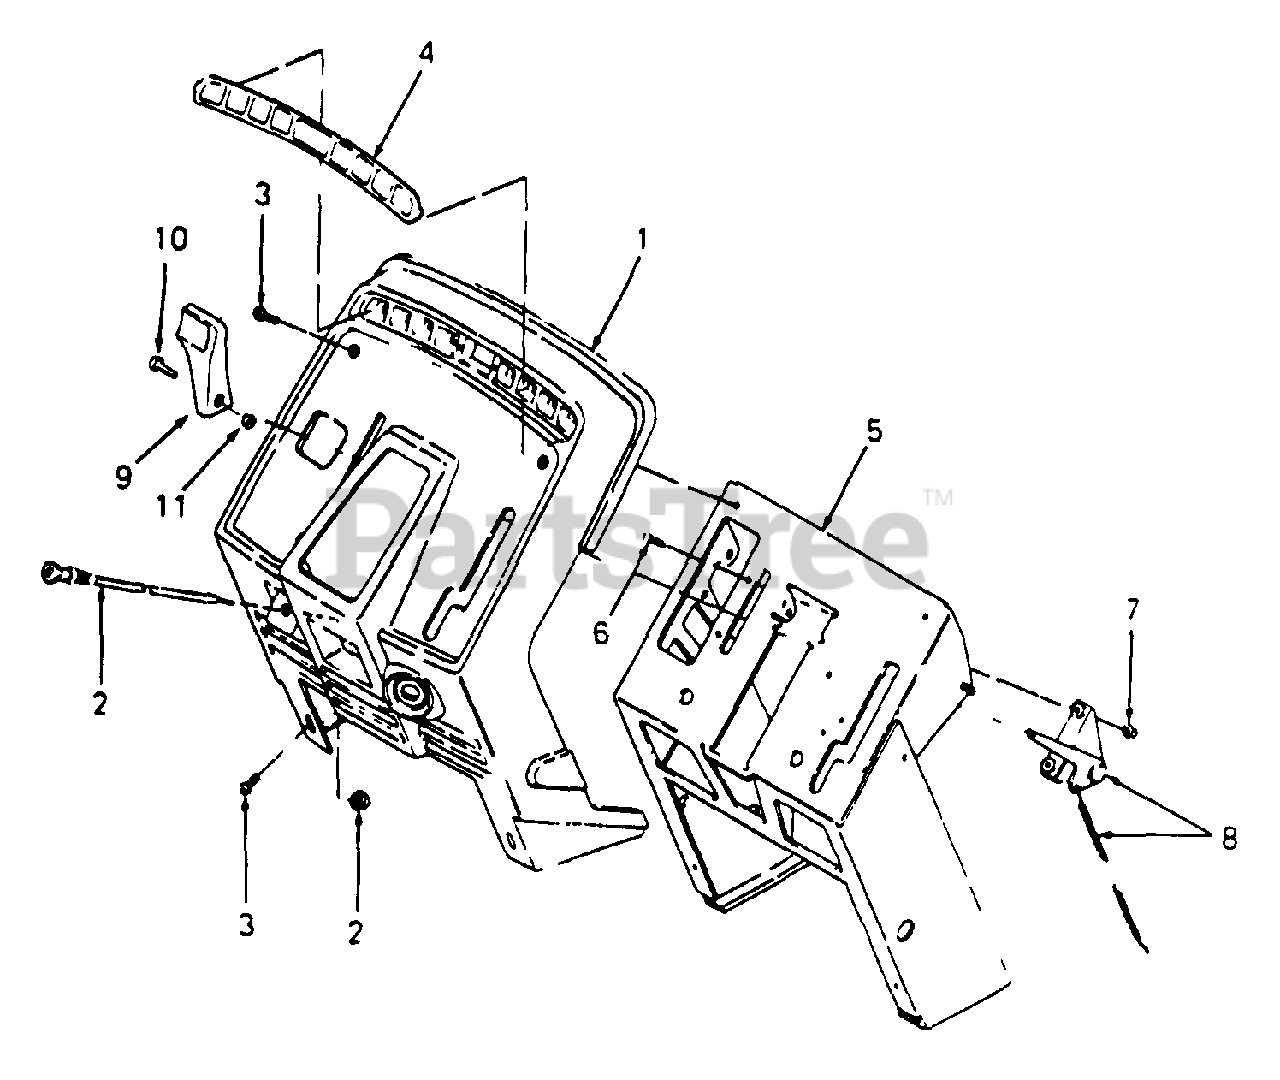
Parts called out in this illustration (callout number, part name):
1	Panel, Instrument
2	Choke Cable w/Nut
3	Screw, Pan Hd Cutting, #10-24 x .75 Lg
4	Label, Dash
7	Nut, Hex Keps, #10-32
8	Control, Throttle
9	Knob, Throttle
10	Screw, Cross Rec Truss Hd, #8-32 x .38 Lg
11	Nut, 8-32
